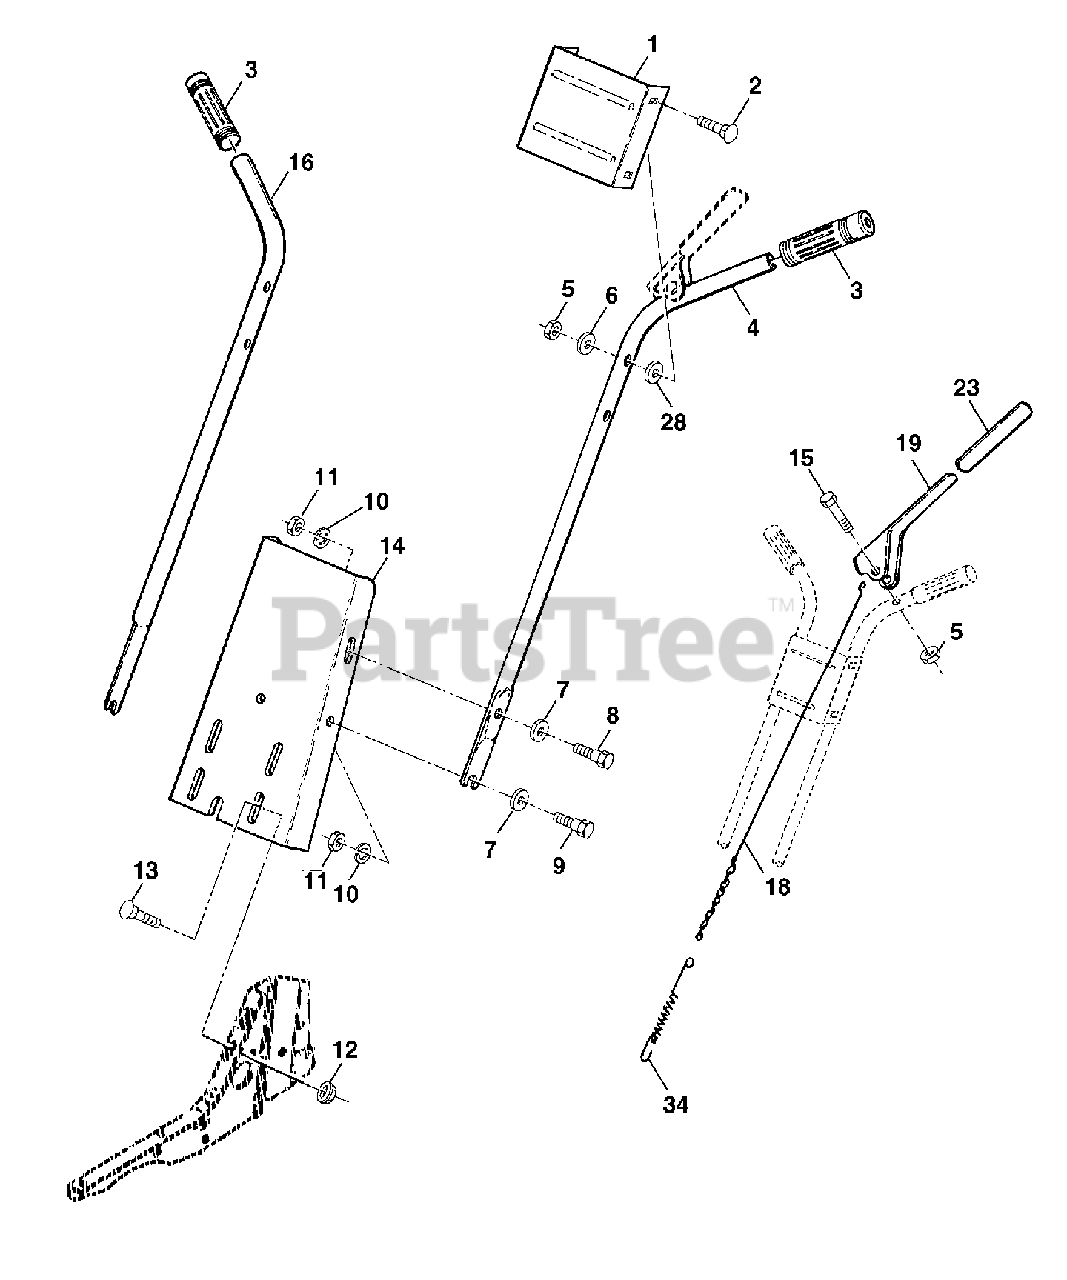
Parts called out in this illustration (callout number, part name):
1	Bracket, Handle
2	Bolt, Carriage 5/16-18 UNC x 1-1/2
3	Grip, Handle
4	Handle, L.H.
5	Locknut, Crown 5/16-18
6	Washer 11/32 x 11/16 x 16 Ga.
7	Washer 3/8 x 7/8 x 14 Ga.
8	Bolt, Hex Hd. 5/16-18 x 1
9	Bolt, Hex Hd 5/16-18 x 3/4
10	Washer, Lock 5/16
11	Nut, Hex 5/16-18
12	Nut, Flanged 5/16-18
13	Bolt, Carriage 5/16-18 x 3/4 Gr. 5
14	Panel, Handle
15	Bolt Fin Hex 5/16-18 x 1-1/2
16	Handle, R.H.
18	Cable Asm Clutch
19	Lever Clutch
23	Grip Handle
28	Washer 13/32 x 13/16 x 12 Ga.
34	Spring
